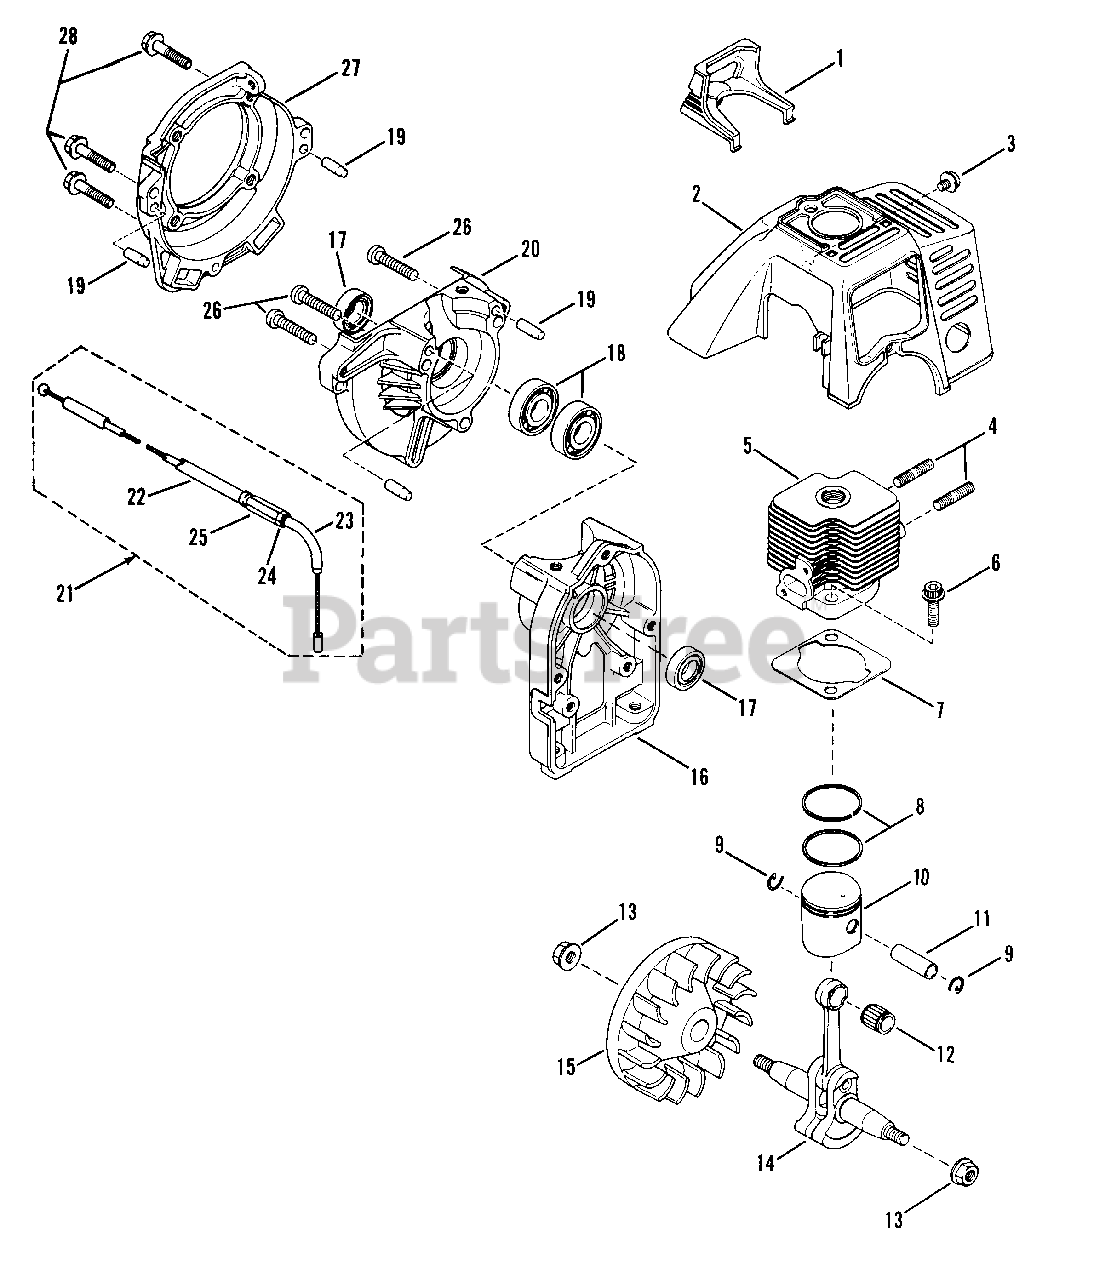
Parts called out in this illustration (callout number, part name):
1	GUARD, Spark Plug
2	COVER, Cylinder
3	SREW, M5 x 12mm
4	BOLT, Stud, M6 x 16mm
5	CYLINDER
6	BOLT, Flange
7	GASKET, Cylinder
8	RING, Piston
9	CLIP, Piston Pin
10	PISTON
11	PIN, Piston
12	BEARING, Needle
13	NUT, Conical
14	CRANKSHAFT ASSM'Y.
15	FLYWHEEL
16	CASE, Starter
17	SEAL, Oil
18	BEARING, Ball
19	PIN, Dowel
20	CASE, Drive
21	CABLE, Throttle Assm'y.
22	CABLE & JACKET
24	NUT, Lock
25	NUT, Adjusting
26	SCREW, M5 x 25mm
27	CASE, Flywheel
28	BOLT/WASHER
